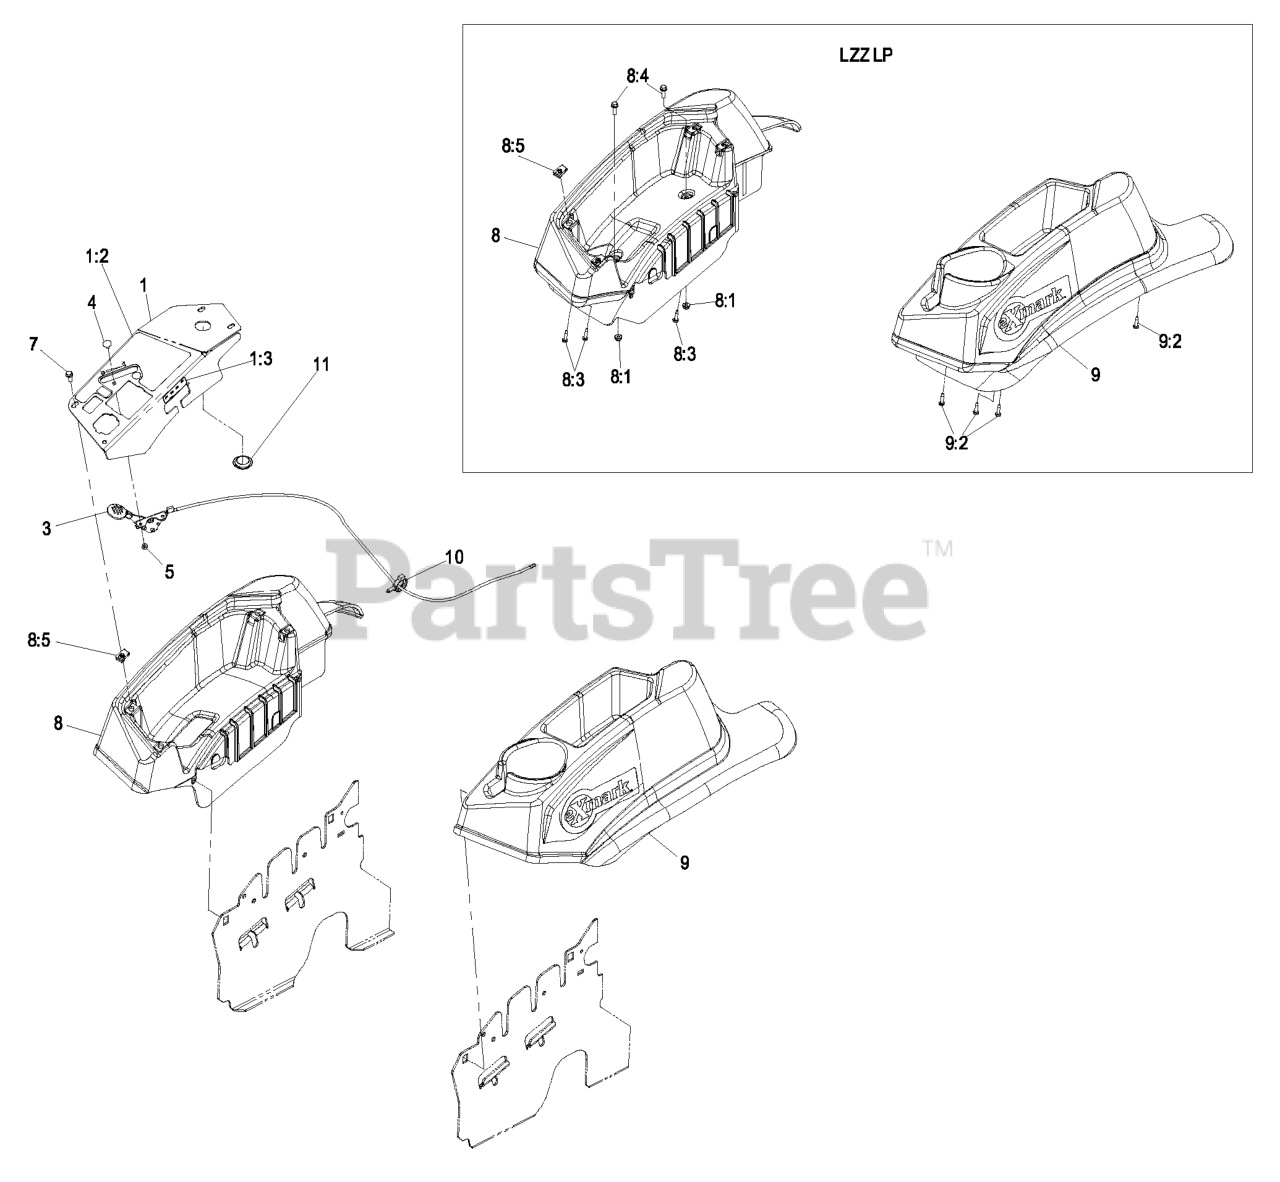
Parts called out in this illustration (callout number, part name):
1	CONTROL PANEL W/DECALS AS
1:2	DECAL,CONTROL PANEL LP
1:3	DECAL-FUSE
3	ASM,THROTTLE CABLE
4	BOLT-CARR
5	NUT-LOCK, NI
7	SCREW-HWH
8	CONSOLE,RH AS ASM
8:3	SCREW,THD FORM,HWH
8:4	SCREW-HWH
9	CONSOLE, LH AS
9:2	SCREW,THD FORM,HWH
10	CLAMP-HOSE
11	PLUG-PLASTIC
